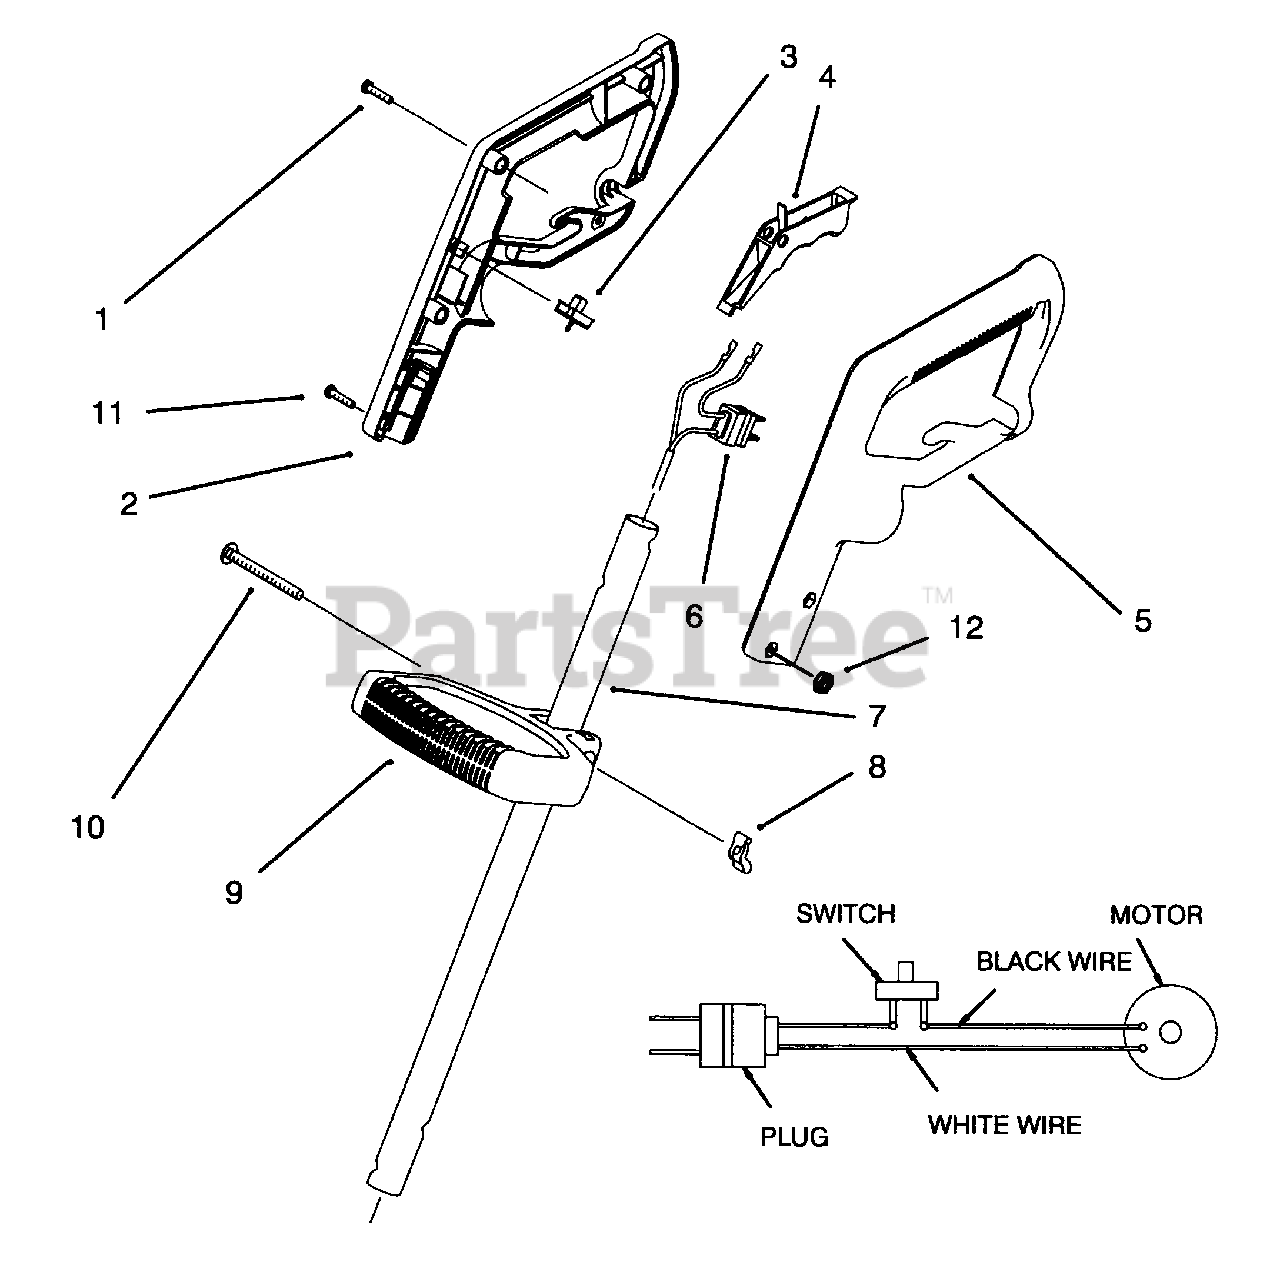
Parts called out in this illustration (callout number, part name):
1	Screw-Pan Hd Tapping
2	Grip-Hand R.H.
3	Switch-Single Speed
5	Grip-Hand L.H.
6	Harness-Wire
9	Handle-Mid
10	Screw-Carriage
11	Screw-Pan Hd.
12	Nut-Lock
